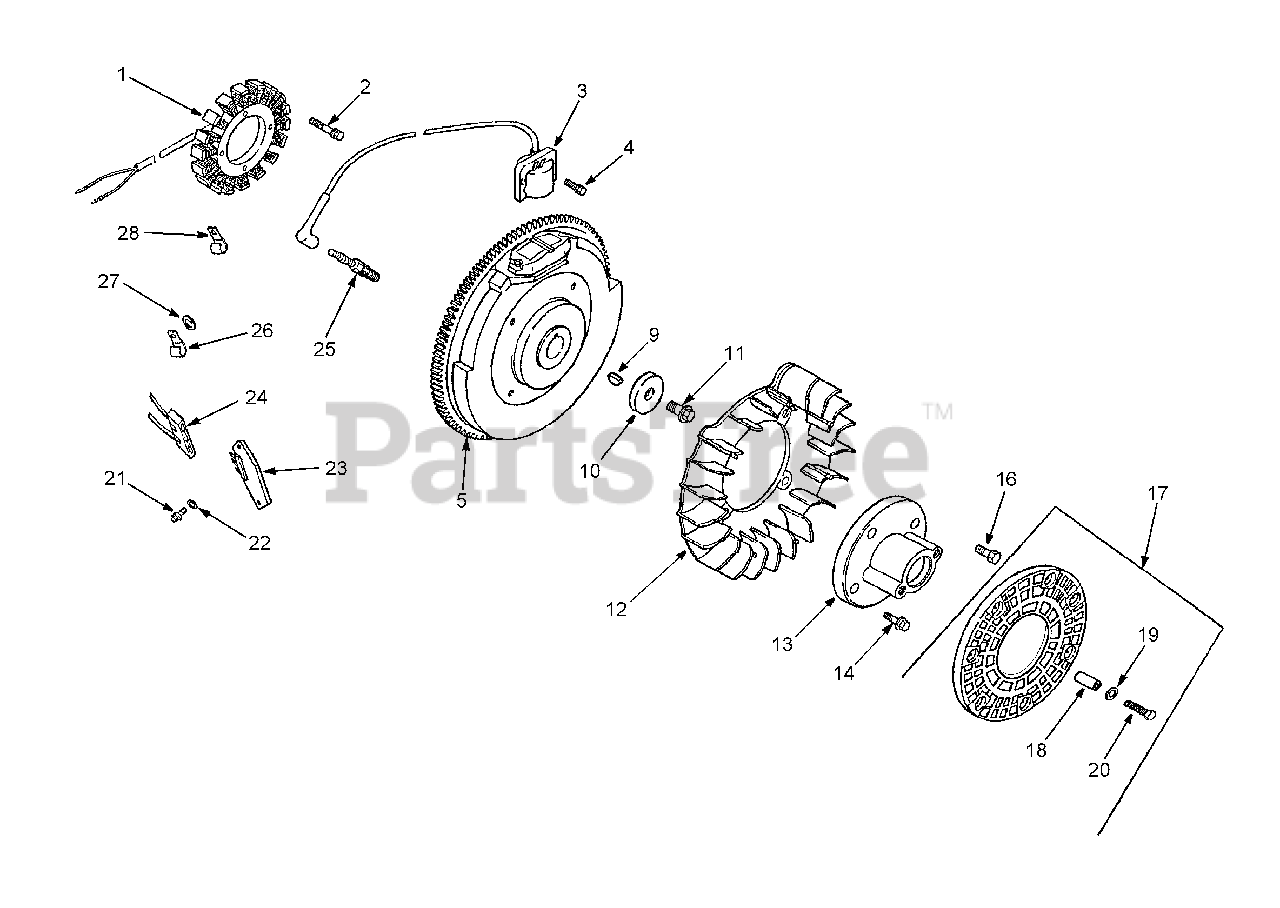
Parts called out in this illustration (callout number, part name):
1	Kit, 15 Amp Stator
2	Screw, Hex Cap M5 x 0.8 x 25
3	Module, Ignition
4	Screw, Hex Socket Hd. M5 x 0.8 x 20
5	Flywheel
10	Washer, Plain 3/8"
11	Screw, Hex Flange M10 x 1.5 x 46
12	Fan
13	Adapter, Drive Shaft
14	Screw, Hex Flange M10 x 1.5 x 90
16	Bolt, Shoulder, M6 x 1.0 x 16
17	Kit,Grass Screen
19	Washer, Plain 3/16"
20	Screw, Hex Cap M4 x 0.7 x 25
21	Screw, Phillips Hd. 11-16 x 7/8"
22	Washer, Plain 3/16"
23	Rectifier-regulator 15 Amp
24	Connector (3 Contact)
25	Spark Plug
26	Clip, Cable
27	Washer, Plain 1/4"
